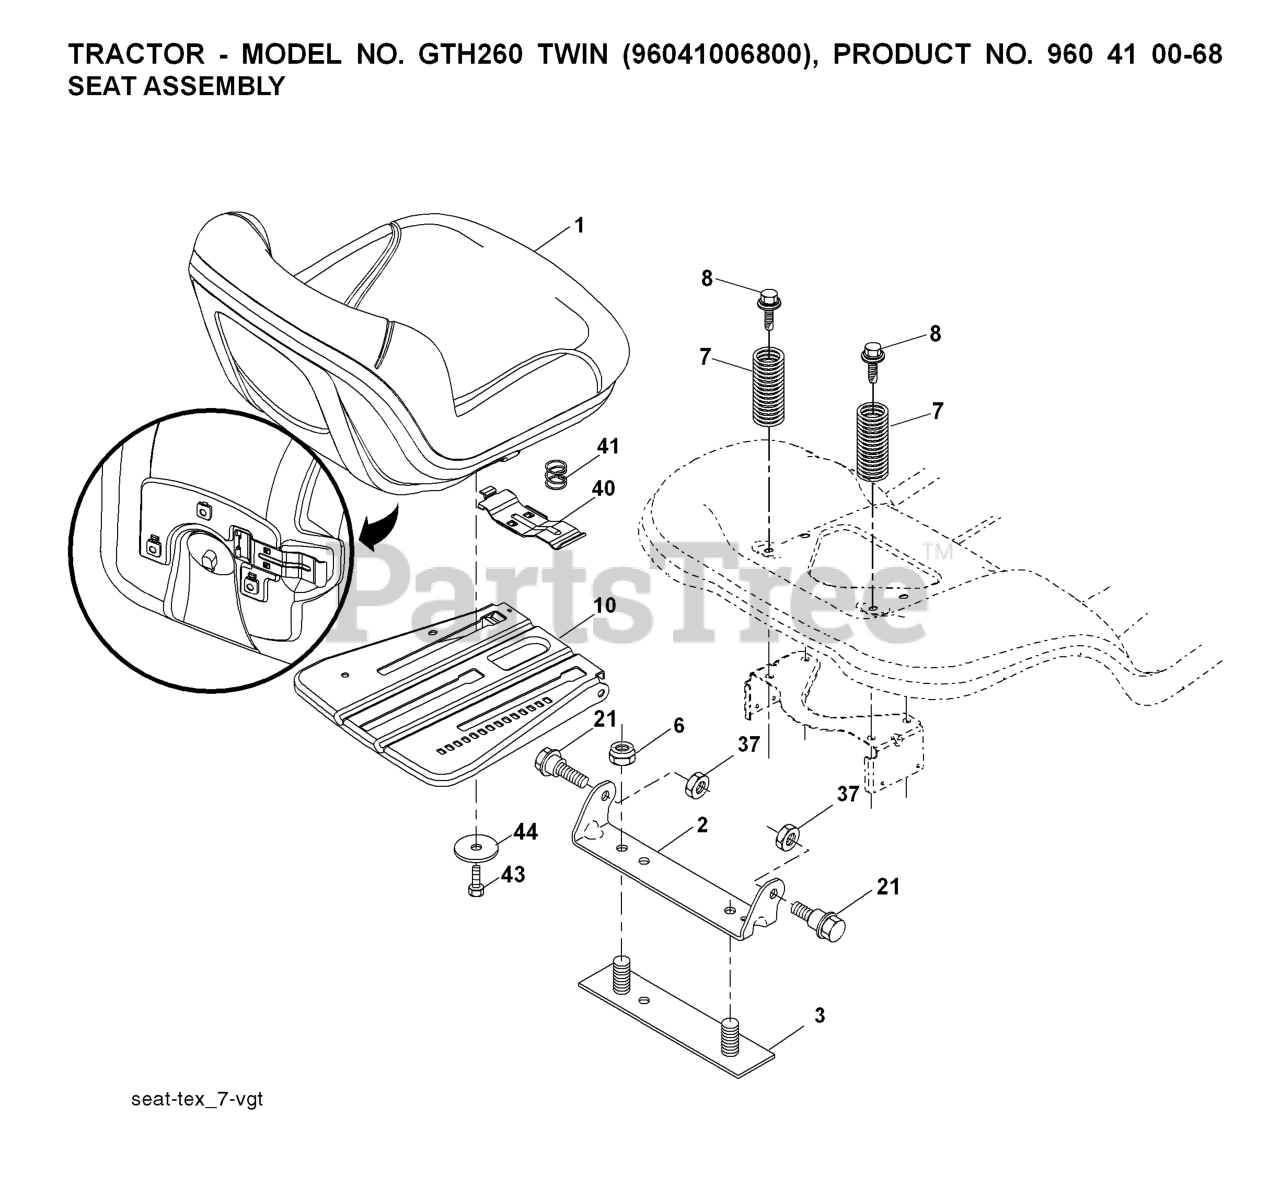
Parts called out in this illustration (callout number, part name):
1	COVER, POWER STEERING
1	SEAT - GREY
2	SCREW, HEX HEAD, TAPPING
2	BRKT.PIVOT.FENDER
3	STRAP
4	RP.DRIVER WHEEL
5	RING, WIRE RETAINER
6	LOBE WHEEL
6	NUT
7	RP.SLIDE.CLUTCH
7	SPRING COMPRESSION
8	SPRING, CLUTCH SLIDE
8	BOLT.5/16-18UNCX3/4 W/SEMS.BLK
9	KEY, SQUARE 1/4 X .875
10	RP.LOBE.AXLE
10	PAN.ASM.SEAT.3PT
11	WASHER TRUST 1"
12	YOKE.WELDMENT.STEER.BLACK
13	BRACKET.STEER.PNT.BLACK
14	Screw 5/16-18 x 1/2 Hex, Self Tapping 5/16-18 x 1/2
15	BRKT.STEER.PIVOT.RH
16	BELLCRANK.STEER
17	PIN, STEERING BELLCRANK
18	SCREW 1/4X20
19	LINK.STEER.YOKE
20	RETAINER CLIP
21	RETAINER CLIP PM
21	BOLT.SHOULDER.5/16-18
22	SPRING LATCH
23	PIN, STEERING LEVER
24	BRACKET.STEER.PIVOT.LH.YZ
37	NUT.71038.31-18.HEX.NYLOCK
40	HANDLE.SLIDE.SEAT.TEX.BLACK
41	SPRING.LATCH.SEAT.TEX
44	WASHER 13/32 X 2-3/8 X 12GA
